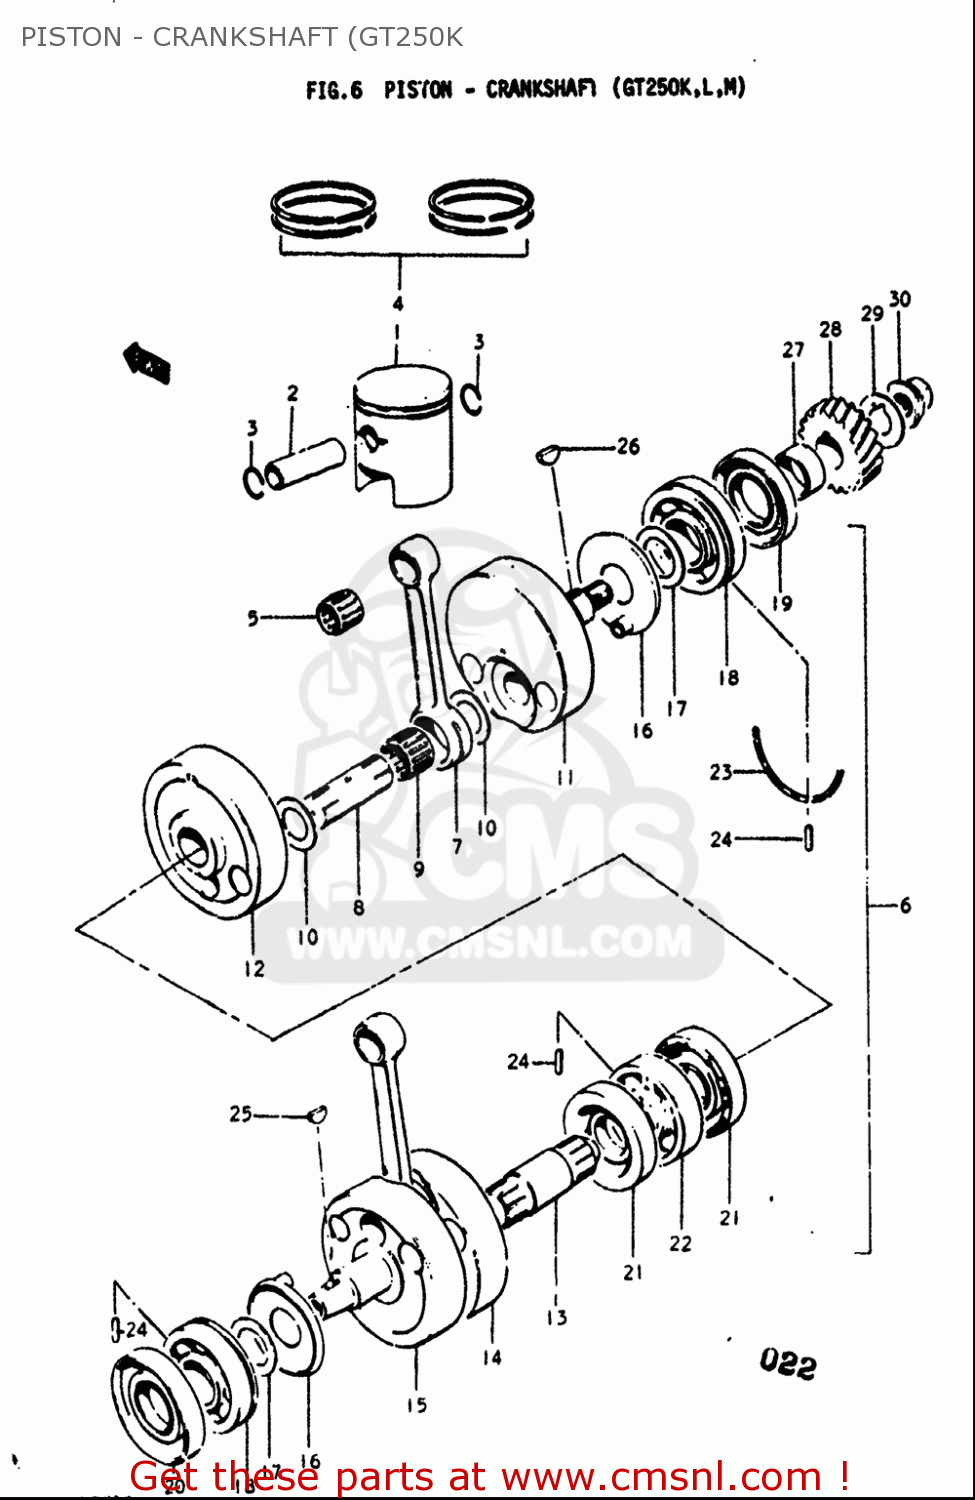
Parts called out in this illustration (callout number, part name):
1	PISTON SET(OS:0.5)
2	PIN,PISTON 16MM
3	RING,SNAP 16MM
4	RING SET,PISTON
5	BEARING(16X21X19.6)
7	CONNECTING ROD
9	BEARING(20X26X16.7)
10	WASHER (20X34X1)
17	SHIM(25X40X1)
18	BEARING(25X65X17)
19	SEAL,OIL
20	SEAL,OIL(25X65X12)
21	SEAL,OIL
24	ROLLER(4X13.8)
25	KEY
26	KEY
29	WASHER
